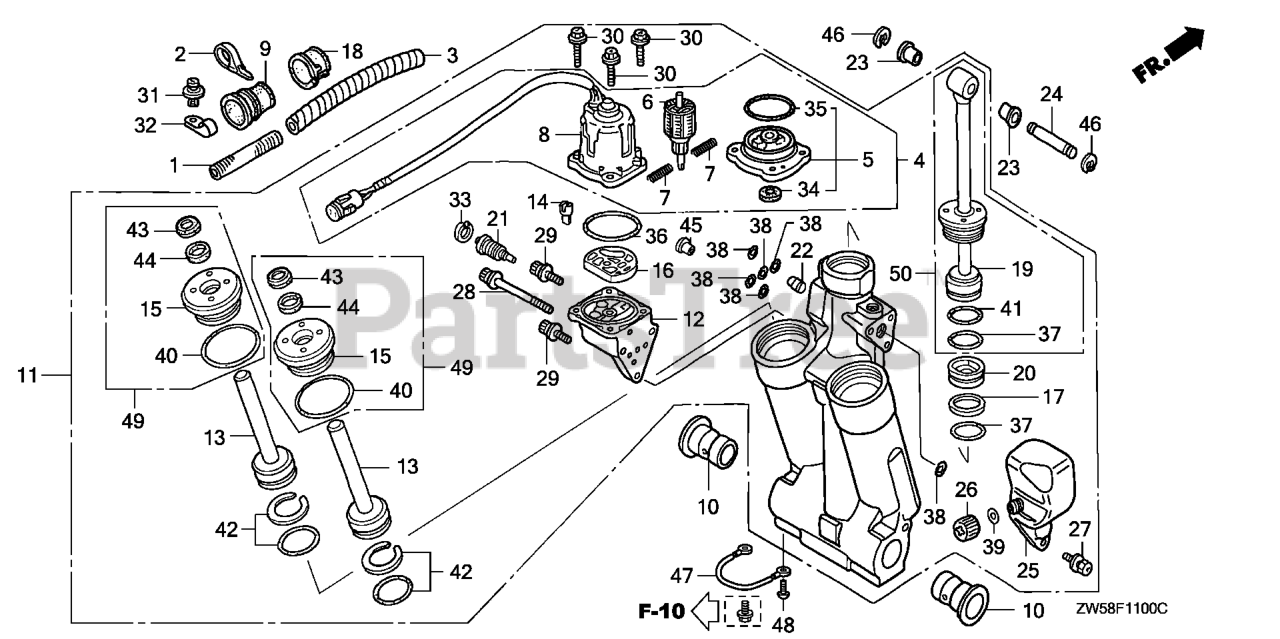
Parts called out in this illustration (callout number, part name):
1	TUBE, CORRUGATE (10MM)
2	BAND (BLACK 3.5X140)
3	TUBE, SPIRAL (12X14.6)
4	MOTOR ASSY., POWER TILT
5	BRACKET ASSY.
6	ARMATURE
7	SPRING, MOTOR
8	YOKE ASSY.
9	GROMMET, CASE (LOWER) (C)
10	BUSH, SWIVEL CASE
11	TRIM-TILT, POWER
12	PUMP ASSY.
13	ROD, PISTON (B)
14	JOINT, DRIVE
16	FILTER (B)
17	RING, BACK-UP
18	BUSH, MOTOR CODE
19	ROD, PISTON
20	PISTON, FREE
21	VALVE, MANUAL
22	VALVE, RESERVOIR
23	BUSH, CYLINDER (LOWER)
24	PIN, CYLINDER (UPPER)
25	TANK, OIL
26	CAP, OIL TANK
27	BOLT, RECESSED
28	BOLT A, SOCKET
29	BOLT B, SOCKET
30	BOLT, HEX.
31	SCREW, RIVET (5X10)
32	CLIP (10.7MM)
33	CIRCLIP (INNER)
35	O-RING (2.0X70.5)
36	O-RING (1.8X69.6)
37	O-RING (3.5X38.7)
38	O-RING (1.8X7.7)
38	O-RING (1.68X7.25)
39	O-RING (1.9X11)
40	O-RING (3.5X35.7)
41	O-RING (3.5X41.7)
42	O-RING SET (3.5X31.7)
43	SEAL, WATER
45	COLLAR, ORIFICE
46	E-RING (15MM)
49	GUIDE, ROD
50	ROD, PISTON
